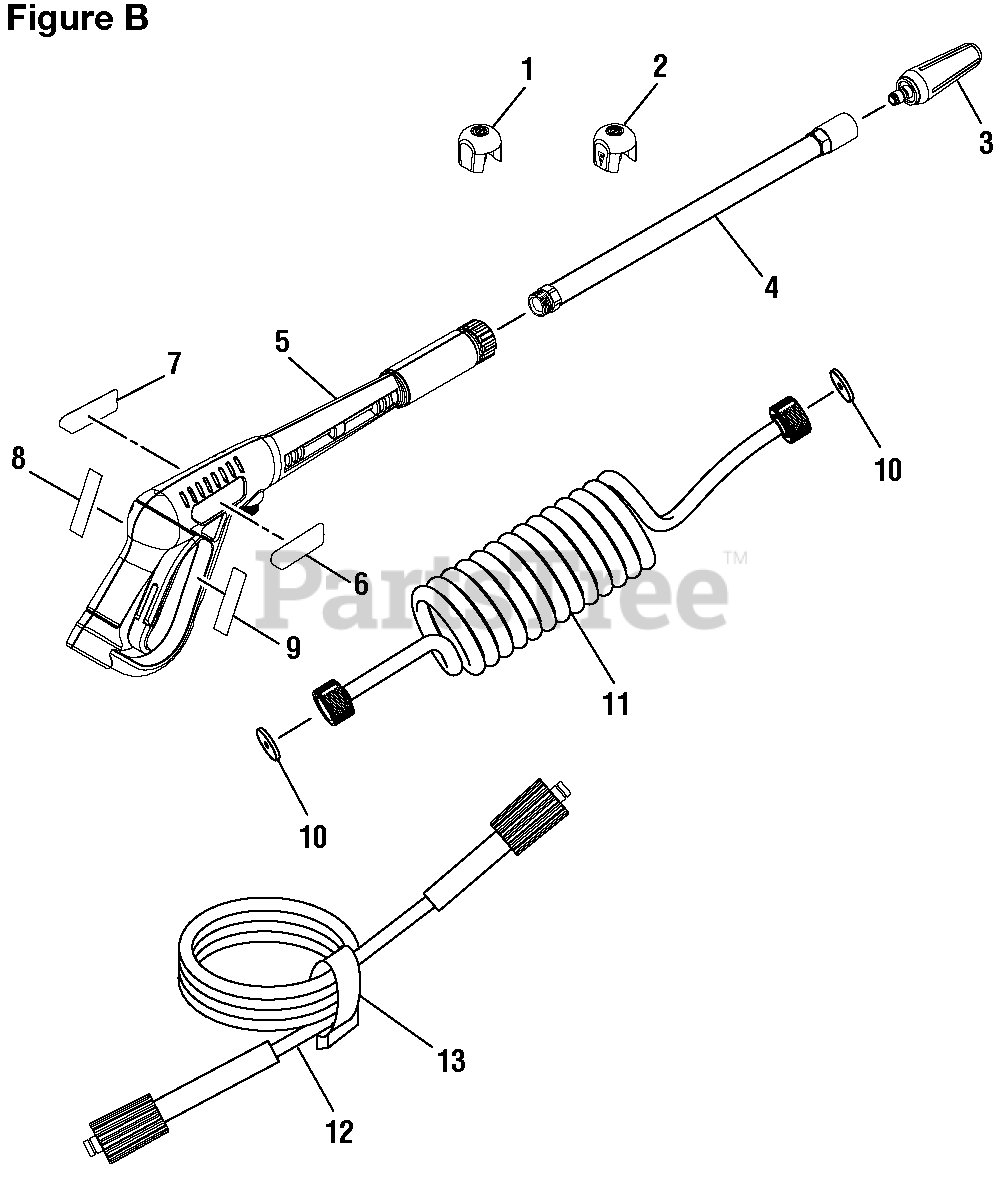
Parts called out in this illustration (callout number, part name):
1	Soap Nozzle
2	High Pressure Nozzle
3	Turbo Nozzle
4	Wand Assembly
5	Trigger Handle Assembly
6	Wand Logo Label
7	Wand Warning Label (English)
8	Wand Rating Label
9	Wand Warning Label (French)
10	Rubber Washer
11	Coil Hose
12	Wand Hose
13	Hose Strap
